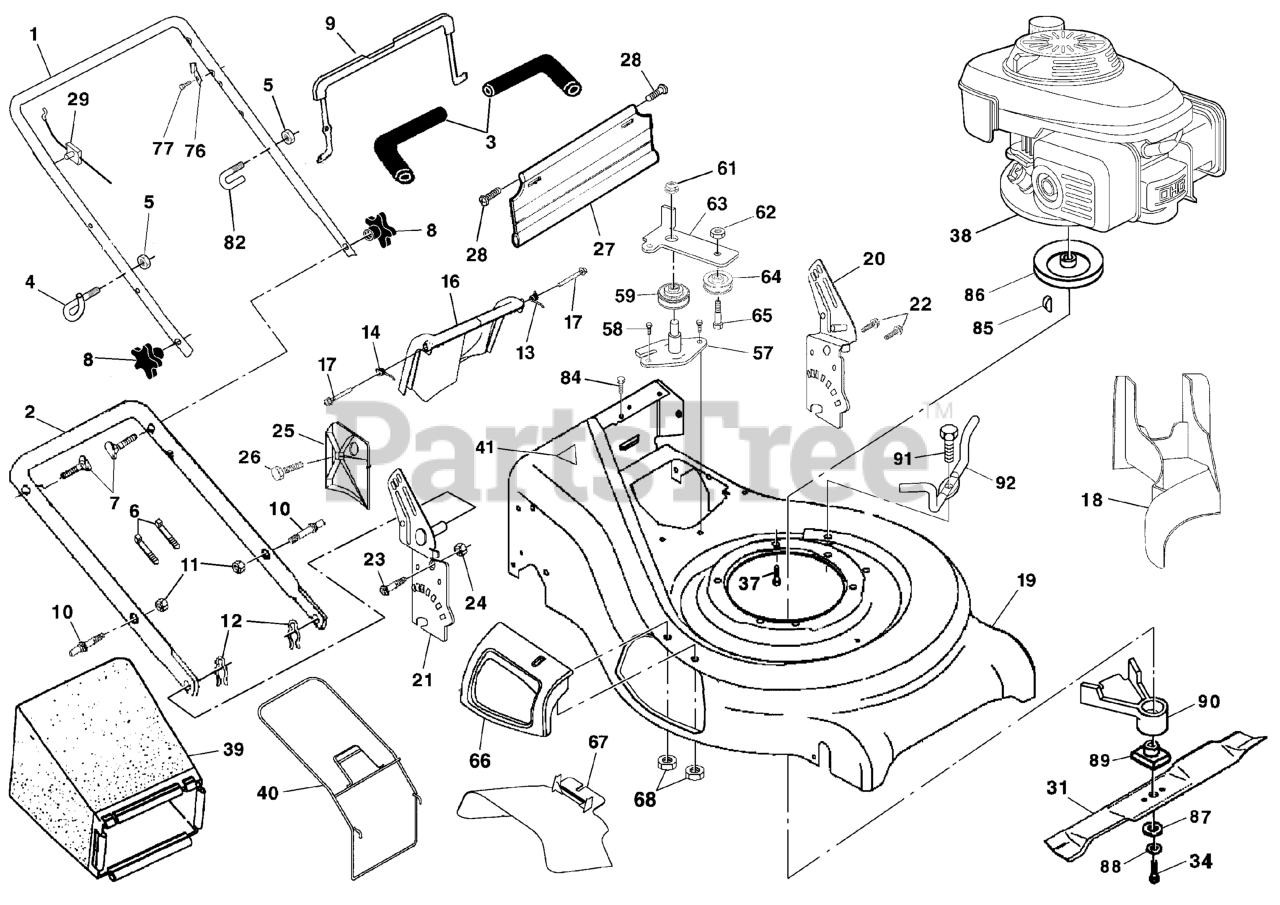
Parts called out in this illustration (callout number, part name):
1	HANDLE.UP.ASM.DSTRT/FLT
2	HANDLE, LOWER
3	GRIP.HANDLE.FOAM.WIDE.(1 SIDE)
4	ROPE, GUIDE
5	NUT
6	TIE GUIDE
7	HANDLE BOLT
8	KNOB.HANDLE.STAR.HUSQ.GRAY
9	BAIL, FLAT AUTO WALK
11	NUT.CENTERLOCK.5/16-
12	HAIRPIN COTTER
13	SPRING.RH.REAR.DOOR.21.RWGD
14	SPRING.LH.REAR.DOOR.21.RWGD
16	DOOR.REAR.PLASTIC.21.RWGD.BLAC
18	PLUG, MULCHER
19	RP KIT.HSG.21.RGD.MC.ORAN
20	HANDLE BRACKET ASM. LH
21	HANDLE BRACKET ASM. RH
22	SELF-TAPPING SCREW 5/16-18X3/4
23	BOLT, HEX HEAD 5/16-18
24	NUT.71038.31-18.HEX.NYLOCK
25	CLIPPING DEFLECTOR
27	SKIRT, REAR
28	HINGE SCREW
29	ENGINE ZONE CONTROL CABLE
31	BLADE.21.PUSH/RWGD/FWG
34	SCREW, HEX HD 3/8-24 X 1-3/8
37	BOLT 3/8-16X1-1/8
39	GRASS CATCHER BAG
40	GRASS CATCHER FRAME
41	DECAL HYT
57	BRACKET ASSEMBLY
59	PULLEY ASSY
61	NUT
62	LOCKNUT
63	IDLER ARM
64	IDLER PULLEY
65	SHOULDER BOLT
66	MULCHER DOOR ASM.
67	DEFLECTOR, DISCHARGE
76	BRACKET UPSTOP
85	HI-PRO KEY
86	PULLEY.ENG.25MMM
87	WASHER,HARDEN
88	LOCKWASHER
89	BLADE ADAPTER
90	DEBRIS SHEILD
91	SCREW
92	BRACKET
